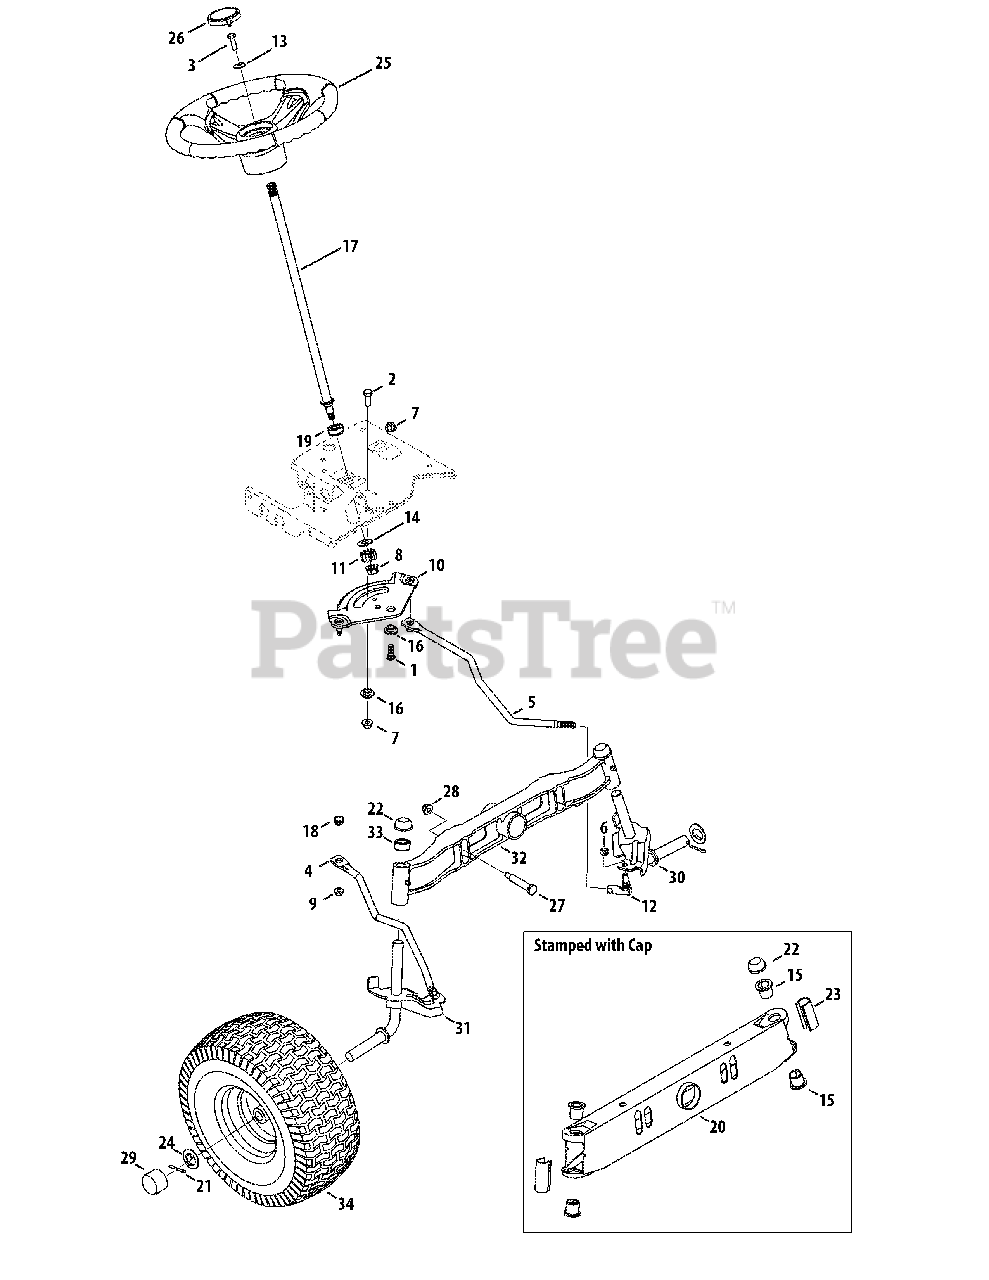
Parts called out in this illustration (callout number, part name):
1	Hex Screw, 3/8-16, 1.00, Gr5
2	Hex Screw, 3/8-16, 1.00, Gr5
3	Hex Screw, 5/16-18, 1.00, Gr5
4	Link, Drag, RH
5	Link, Drag, LH
6	Nut, Hex Lock, 3/8-24
7	Nut, Flange Lock, 3/8-16, Grf
8	Nut, Flange Lock, 7/16-20
9	Nut, Flange Lock, 5/16-18, Gr5
10	Gear, Steering, 11/90 Ratio
11	Gear, Pinion, Steering
12	Ball Joint, 7/16-20, Lock
13	Washer, Flat, .406 x .875 x .105
14	Washer, Flat, .51 x 1.12 x .06
15	Flange Bearing
16	Spacer, Shoulder, .38 x 1.00 x .31
17	Shaft, Steering, .625 OD x 24.25
18	Plastic Bushing .380 ID
19	Hex Flange Bearing
20	Pivot Bar Axle Assembly
21	Cotter Pin, 5/32 x 1.25
22	Push Cap, 3/4
23	Pivot Bar End Cap
24	Flat Washer, .781 x 1.59
25	Steering Wheel
26	Steering Wheel Cap, TB Logo
27	Shoulder Bolt, .5 x 2.38, 3/8-16
28	Flange Lock Nut, 3/8-16
29	Hub Cap, Standard
30	LH Axle Assembly, .750 (42" Deck)
30	LH Axle Assembly, .750 (50" Deck)
31	RH Axle Assembly, .750 (42" Deck)
31	RH Axle Assembly, .750 (50" Deck)
32	Pivot Bar Axle Assembly
33	Spacer, Shoulder, .71 x .125 x .56
34	Wheel Assembly Complete, 15x6
